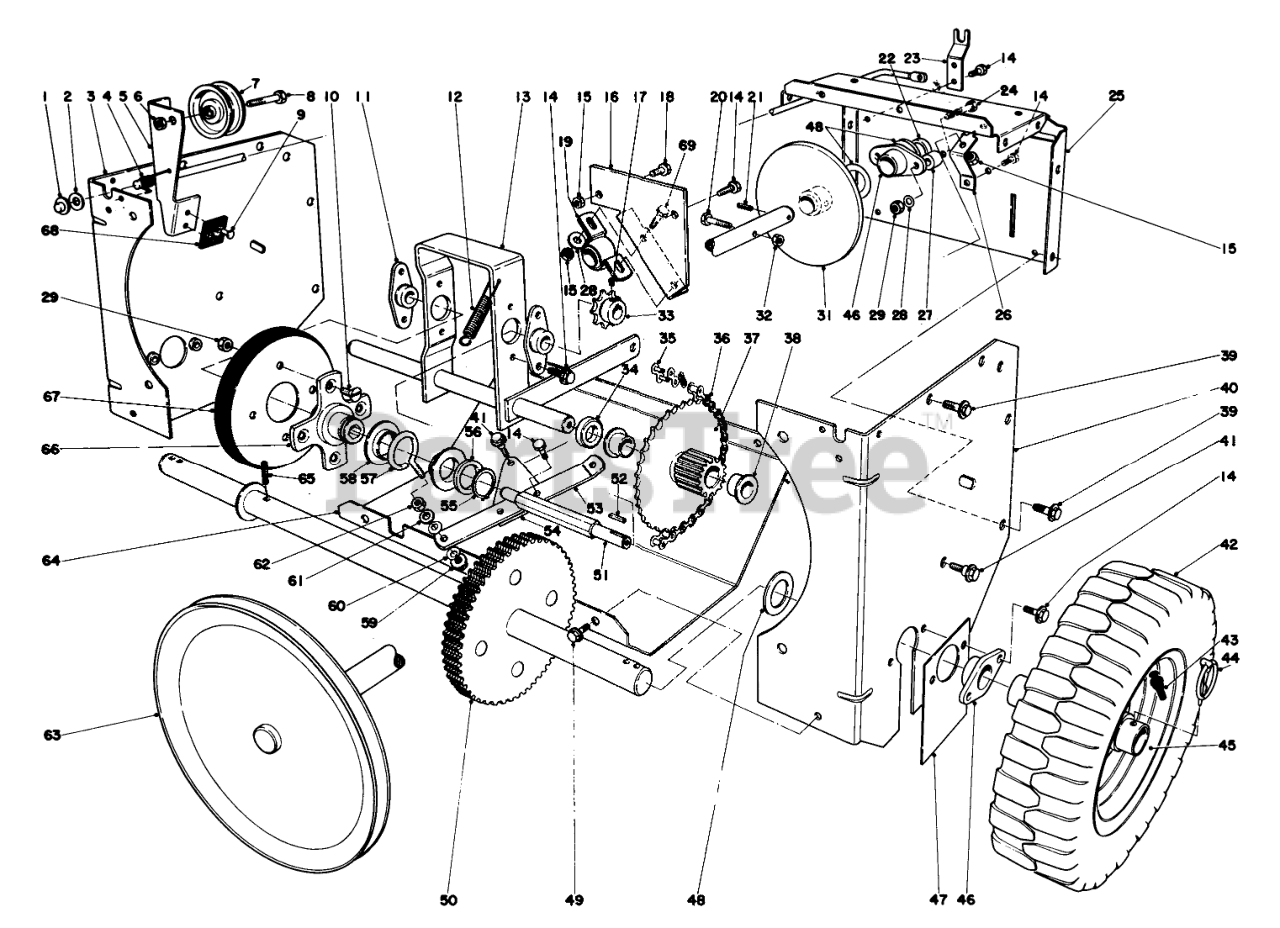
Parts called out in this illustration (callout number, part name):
1	PUSH NUT
2	WASHER-FLAT
3	RH TRACT SIDE PLT R
4	TORSION CLUTCH SPRING
5	Clutch Rod (Incl. Ref. #9 & 68)
6	NUT-HEX
7	PULLEY-IDLER
8	SCREW-HH
9	.185 DIA X .375 RT +
10	5/16-18X5/8 FLT HD MS
11	BEARING-WHEEL, FRICTION
12	TENSION SPRING
13	PIVOT SHAFT WA B
14	SCREW-HWHTF
15	NUT-LOCK, NI
16	SHAFT SUPT BRKT B
17	SCREW-HSH
18	SCREW-HH
19	PILLOW BLOCK BRG
20	SCREW-HH
21	PIN-ROLL, SLOTTED
22	DRIVE SHAFT SPACER
23	CLUTCH ROD SUPPORT
24	SCREW-HH
25	CENTER FRAME R
26	PIVOT BRACKET
27	BRG STANDOFF
28	WASHER-PLAIN
29	Nut
31	FRICTION PLT WA
32	NUT-LOCK, CONE
33	SPROCKET
34	COSHAFT SPACER
35	LINK-CONNECTING
36	ROLLER-CHAIN
37	Gear& Bushing (Incl. Ref. #38)
38	BUSHING
39	SCREW-HHFTF
40	LH TRACT SIDE PLT R
41	SHOULDER SCREW
42	Tire
43	STEM-VALVE
44	PIN-LYNCH
45	Wheel
46	AXLE BEARING
47	Cover
48	WASHER
49	SCREW-HWH
50	AXLE & GEAR WA
51	FRICTION WHL SHAFT
53	SHIFT LINKAGE
54	PIVOT PLATE
55	RING-RETAINING
56	WASHER-THRUST
57	SLIDER RING COLLAR
58	SLIDER RING
59	NUT-LOCK, FLANGE
60	WASHER-SPRING
61	WASHER-FLAT
62	Nut
63	PULLEY/SHFT WA
64	LOWER SHIELD R
65	PIN-ROLL, SLOTTED
66	TRACTION DISC HUB
67	Disc
68	BRAKE PAD
69	SCREW-HH
